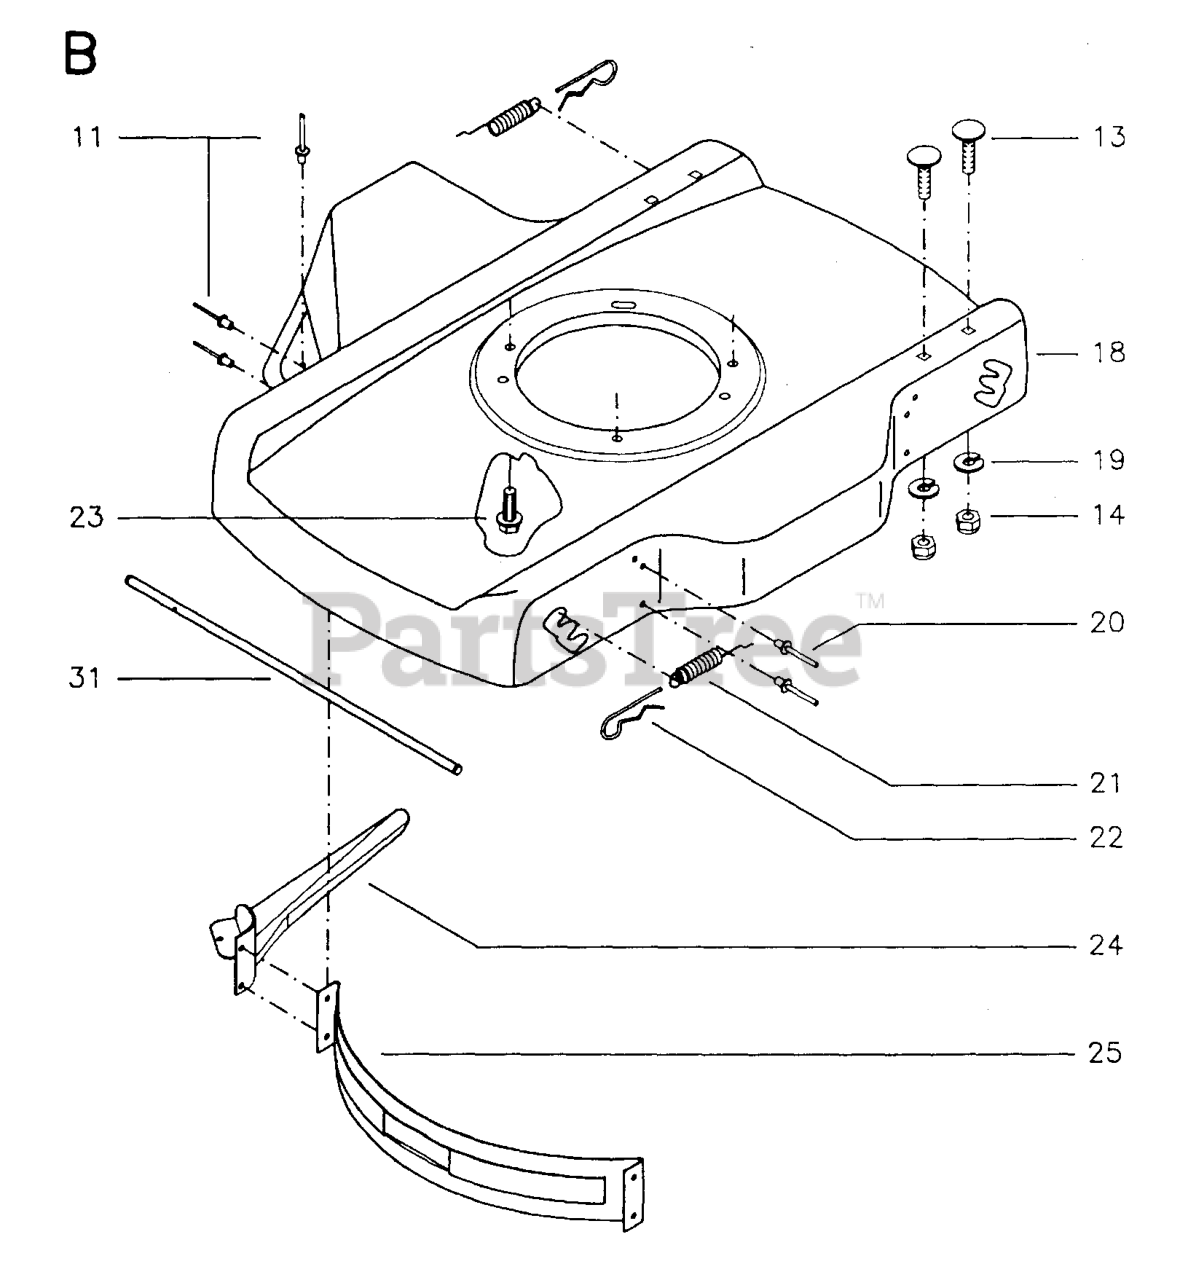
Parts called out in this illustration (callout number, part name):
11	REPL BY 516 92 38-00
14	NUT
19	SPRING WASHER
20	RIVET
